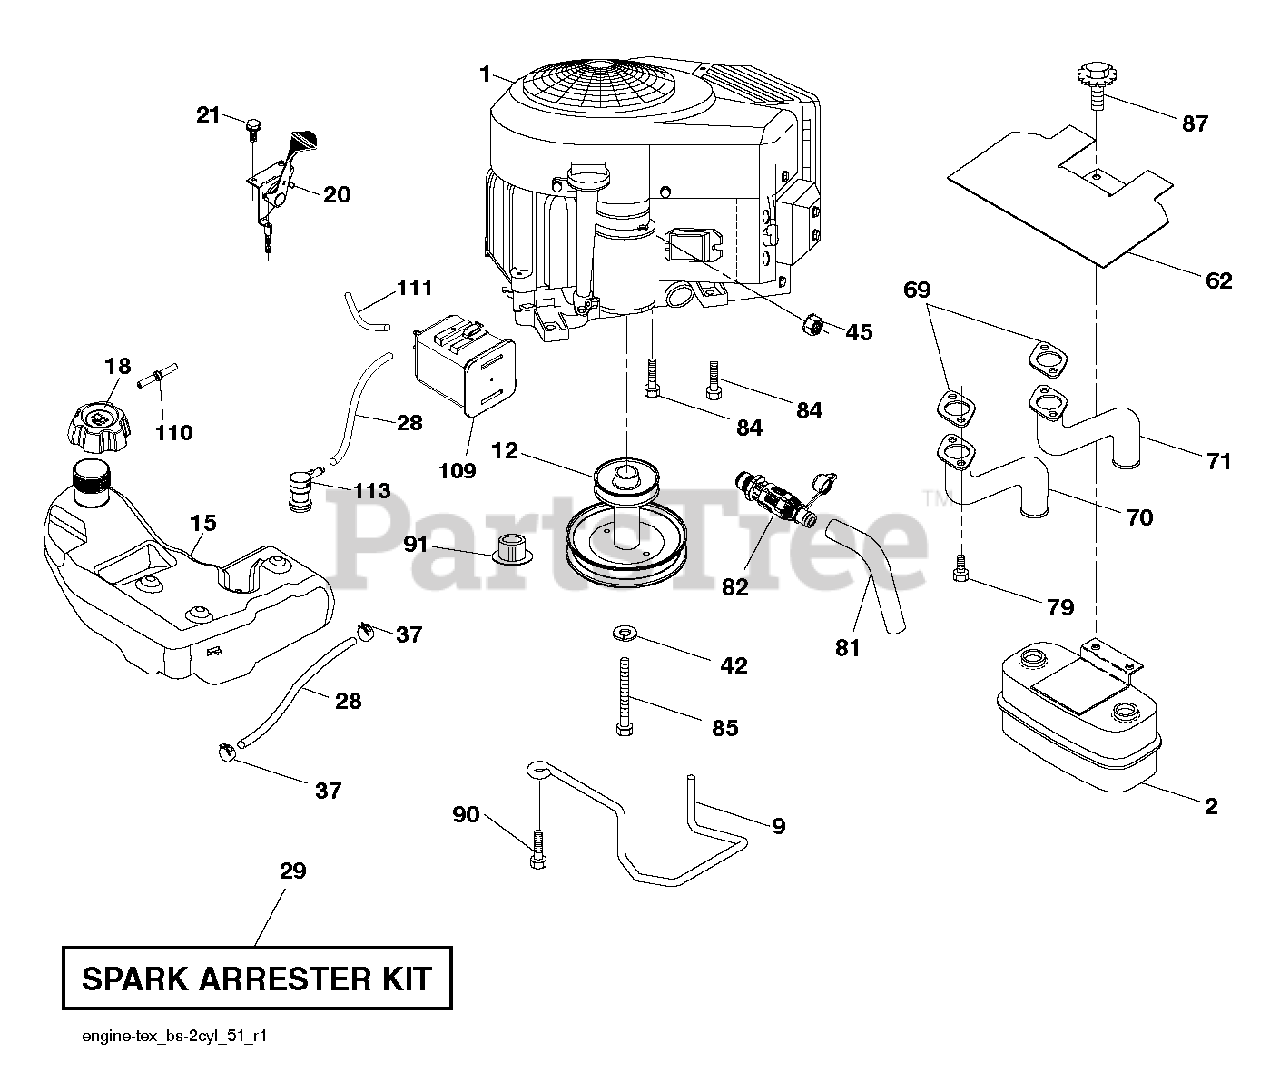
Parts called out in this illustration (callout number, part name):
2	MUFFLER.TWIN.CYL.LOW.TONE
9	KEEPER.BELT.ENGINE.4.2
12	PULLEY ENGINE
15	TANK.ASM.FUEL.3GA.CARB
18	CAP ASM.FL.RTCHT.3"GRY.E10
21	SCREW.#10 X 0.750.BOS (2 2)
28	LINE.FUEL.64"REAR.EMIS
29	KIT.SPARK ARRESTOR(392390 B&S)
37	HOSE CLAMP
42	LOCKWASHER
45	NUT
62	SHIELD.HEAT.MUFFLER
69	GASKET.MUFFLER
70	RP.EXHAUST.TUBE.LH.BS/TWIN
71	RP.EXHAUST.TUBE.RH.BS/TWIN
79	SCREW.SOCKET.HEAD.5/16-18
81	TUBE, DRAIN OIL ASM.
82	VALUE.OIL.DRAIN
84	SCREW.3/8-16
85	BOLT HEX 7/16-20X4-1/4"
87	BOLT, 5/16-18 X 1 3/4
90	SCREW 3/8-16X1
91	BUSHING.1.375OD
109	CANNISTER, CARBON
110	VALVE.ASM.ANTI-SLOSH
111	RP PURGE LINE
113	VALVE.SLANT.CARTRDG.90 DEG.TEX
